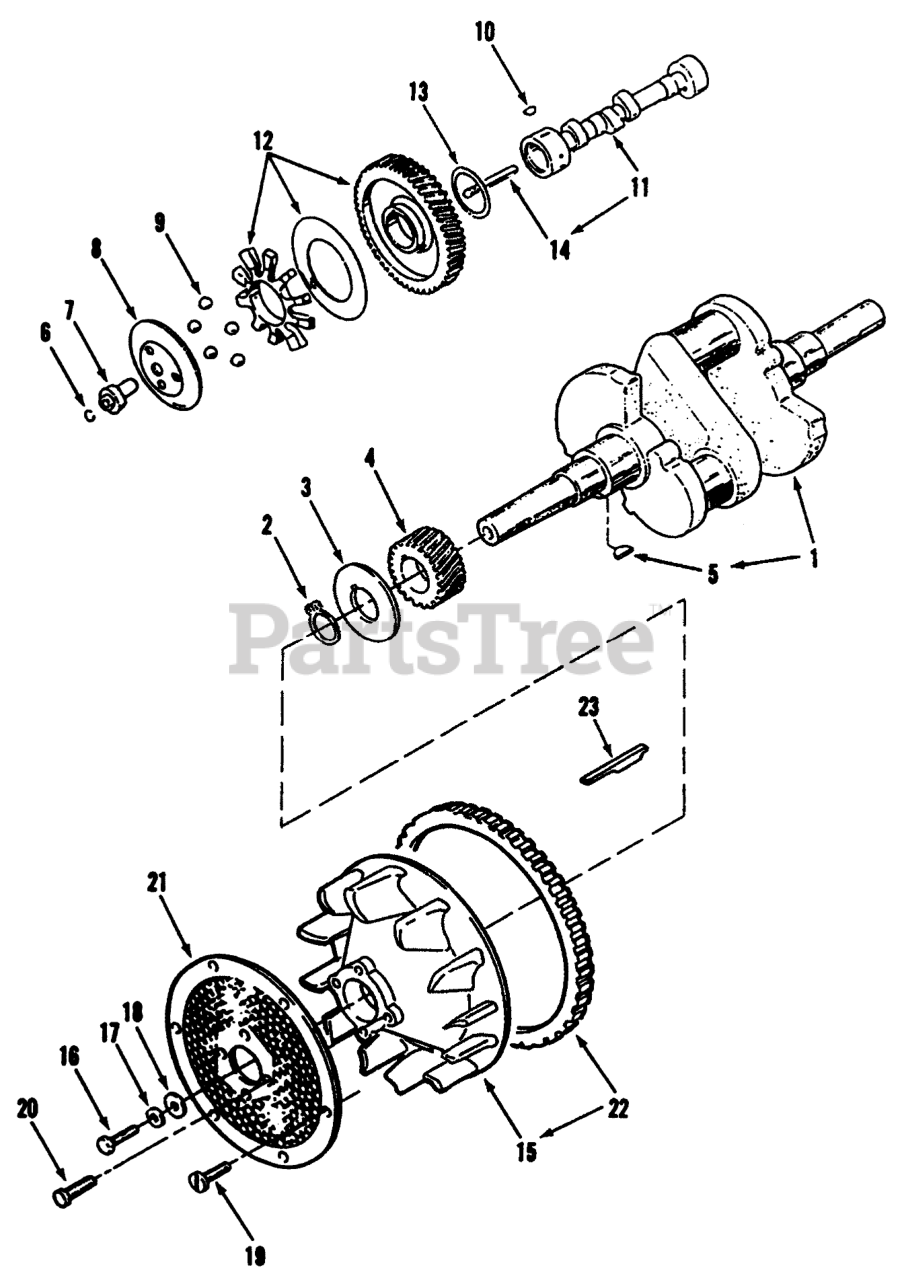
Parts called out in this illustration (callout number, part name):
1	Crankshaft
3	WASHER
7	HUB-GOVERNOR CUP
8	CUP-GOVERNOR
9	BEARING
11	Camshaft (Incl. Item 13)
12	Camshaft Gear (Incl. Gear, Spacer, & Plate)
13	WASHER-THRUST
14	PIN-CENTER
15	Flywheel (Incl. Ring Gear)
16	SCREW
17	WASHER-FLAT
18	WASHER-FLAT
19	LOCK SCREW
20	SCREW - CAP HEX HEAD
21	Screen
23	KEY-FLYWHEEL
